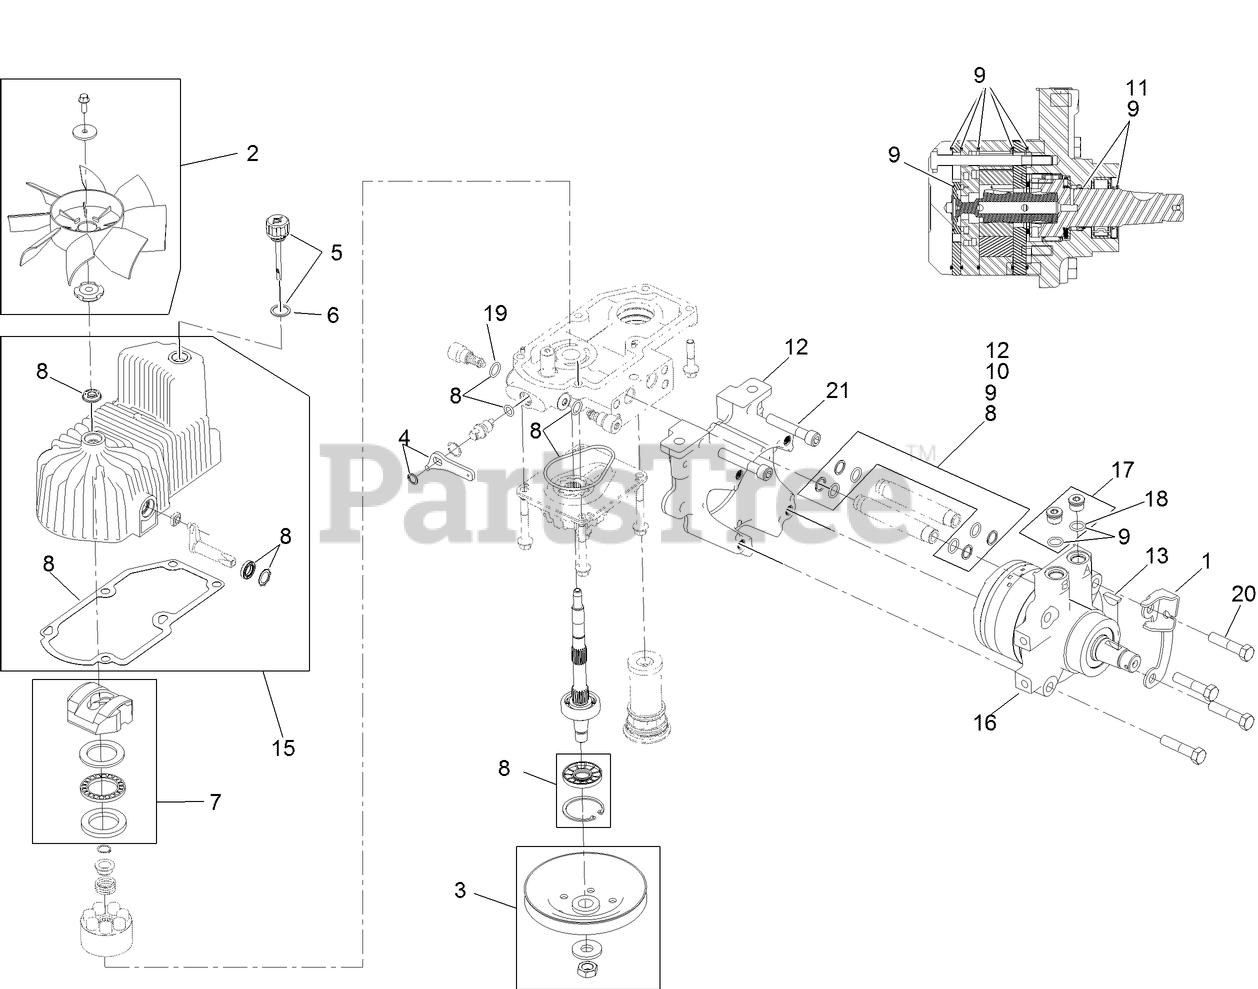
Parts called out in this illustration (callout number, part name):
1	BRACKET-ANCHOR, CABLE
2	FAN KIT
3	PULLEY KIT
4	HANDLE-BYPASS VALVE, HYDRO
5	DIPSTICK-HYDRO W/GASKET
6	GASKET-DIPSTICK, HYDRO
7	SWASH BLOCK KIT
8	PUMP SEAL KIT
9	MOTOR SEAL KIT
10	TUBE SEAL KIT
11	OUTPUT SHAFT SEAL KIT
12	NOSE CUP-UHT
13	KEY-WOODRUFF
15	HOUSING-HYDRO, RH
16	MOTOR-HYDRAULIC, RH 280CC
17	MAGNETIC PLUGS SERVICE KIT
18	O-RING
19	O-RING-CHECK VALVE
20	SCREW HH
21	SCREW-HSH
